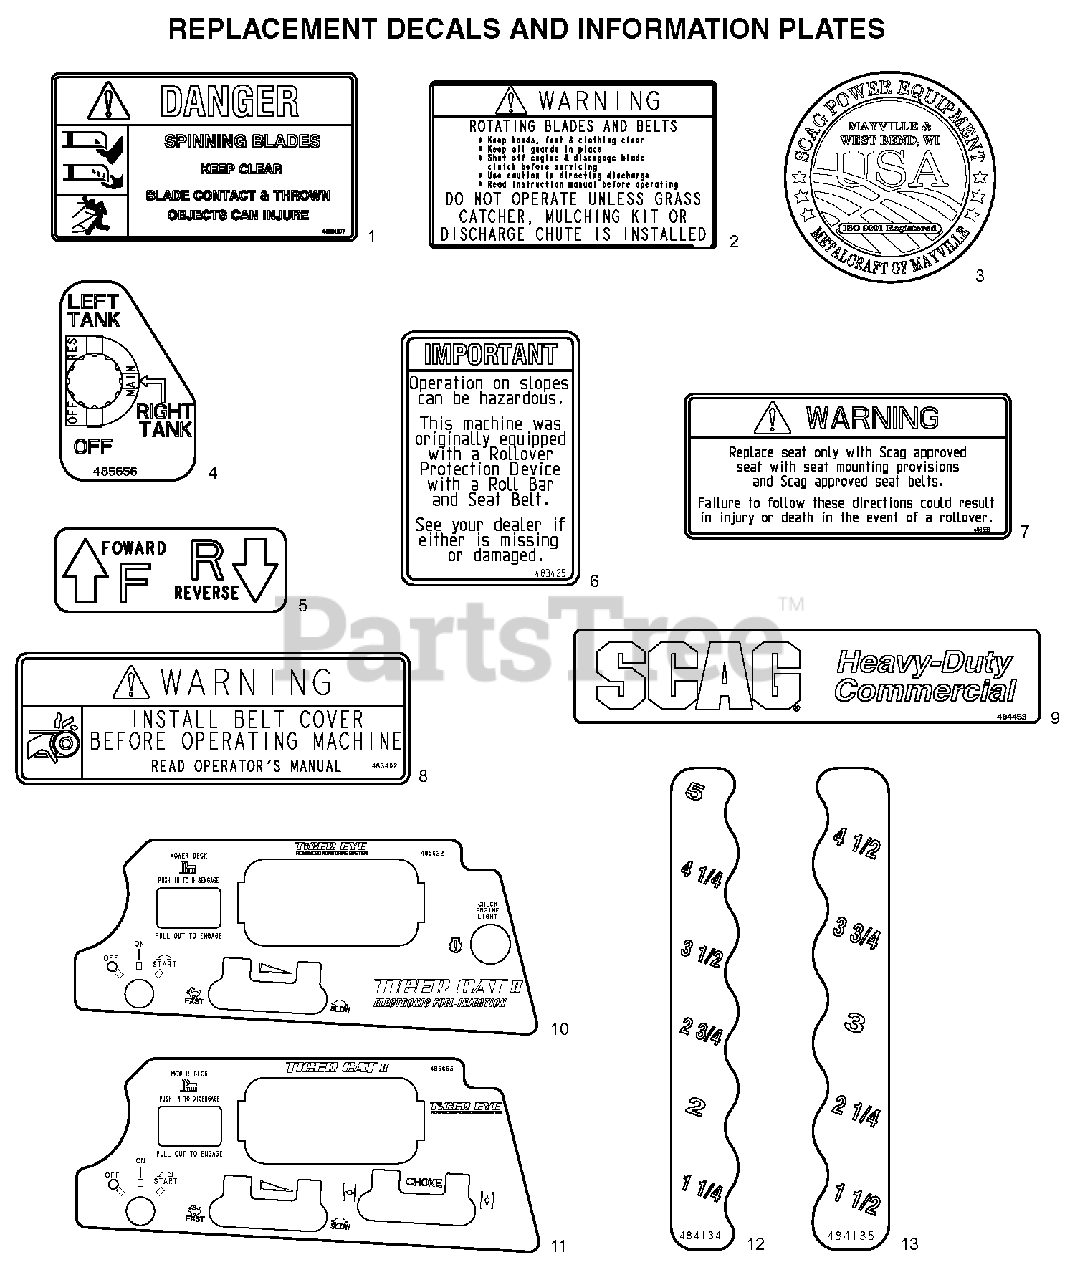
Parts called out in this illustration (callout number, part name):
1	Decal, Danger-Spinning Blades
2	Decal, Warning-Rotating Blades
3	Decal, Metalcraft - USA
4	Decal, Fuel Valve Position
5	Decal, Traction Control
6	Decal, ROPS
7	Decal, Seat Replacement
8	Decal, Belt Cover
9	Decal, Heavy Duty Commercial
10	Decal, Instrument Panel - EFI
11	Decal, Instrument Panel
12	Decal, Deck Height - LH
13	Decal, Deck Height - RH
